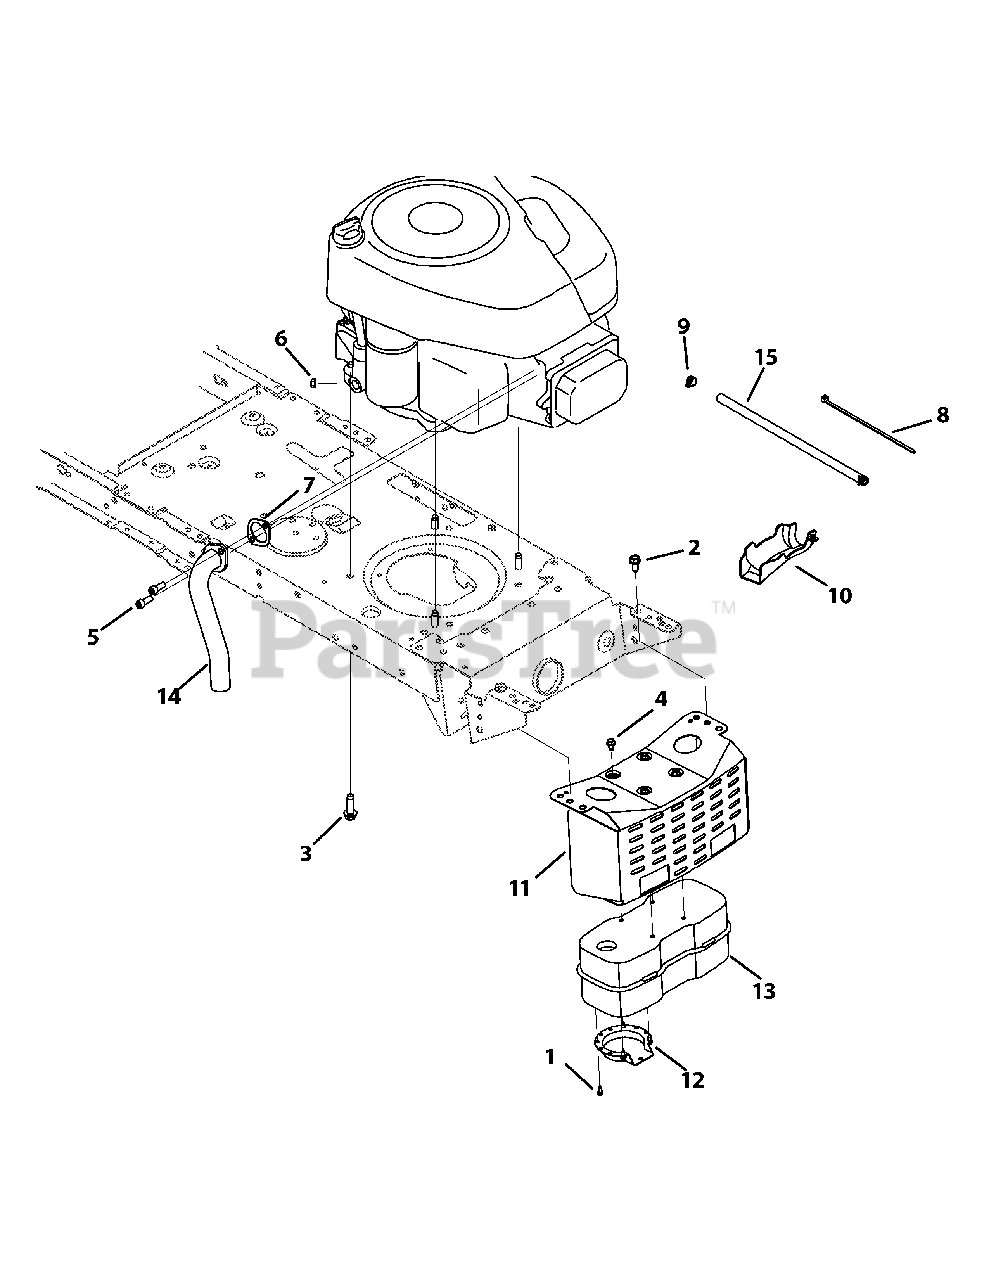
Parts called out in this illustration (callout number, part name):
1	Screw, 8-18 x .500
2	Screw, 5/16-18 x .750
3	Screw, 3/8-16 x 1.000
4	Screw, 1/4-20 x 5.00
5	Socket Screw, 5/16-18 x .750
6	Sems Nut, 1/4-20
7	Exhaust Gasket
8	Cable Tie
9	Hose Clamp, .490 Diameter
10	Oil Drain Sleeve
12	Muffler Deflector
13	Single Inlet Muffler
14	Exhaust Pipe, Single Briggs
15	Fuel Hose, Low Permeation
